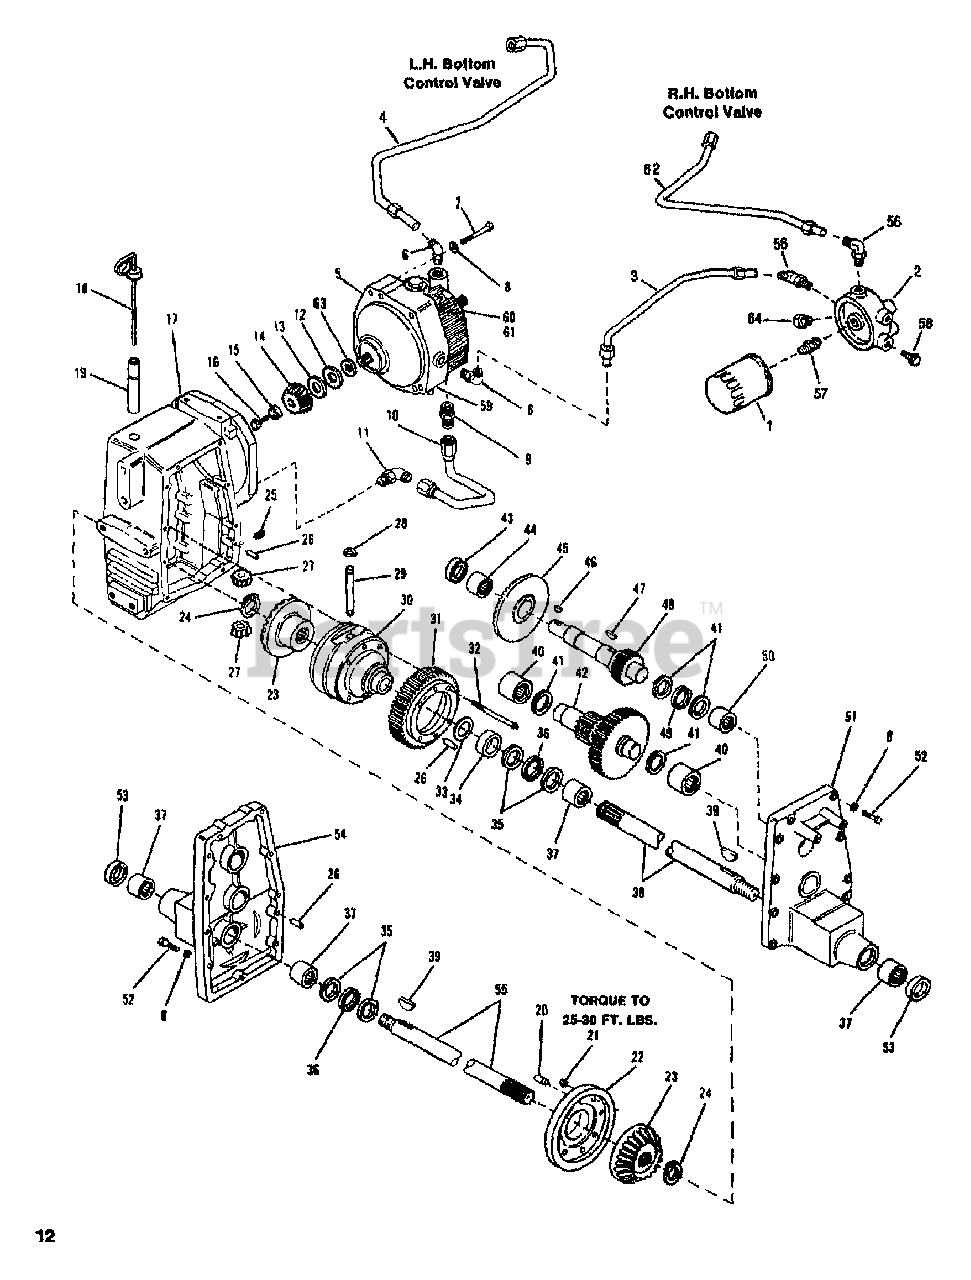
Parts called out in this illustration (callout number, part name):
1	FILTER-OIL
3	ASSM-RETURN TUBE
4	ASSM-TUBE
5	TRANSMISSION-HYDRO
6	ELBOW
7	SCR-HH 3/8-16X2.75 G5 ZP
8	WASHER-LK .375 @ DEPL
9	CONNECTOR
11	ELBOW
12	WASHER-SHIM
13	WASHER-SHIM
14	PINION-BEVEL
15	SPACER-1.0X.25X.25
16	SCR-HH 1/4-20X.625 G5 ZP
17	HOUSING-TRANSAXLE
18	DIPSTICK
20	PIN-.312X.75
21	NUT-HEX/LK 5/16-18 G5ZP
22	COVER-DIFFERENTIAL
23	GEAR-23T
24	RING-HEAVY EXT HD 1.0 ID
25	PLUG-PIPE
26	PIN-DOWEL .375X1.00 ZP
27	PINION-10T
28	RING-RETAIN .625 ID
29	KIT-PINION SHAFT
30	CARRIER-DIFFERENTIAL
31	GEAR-AXLE 47T
32	SCR-HFLK 5/16-18X4.00 ZP
33	SHIM-1.875X1.013X.015
34	SPACER-1.5X1.01X.45
35	RACE-THRUST
36	BEARING-THRUST
37	BEARING-NEEDLE
38	AXLE-RH
39	KEY-WOODRUFF .312X1.12
40	BEARING-NEEDLE
41	RACE-THRUST
42	ASSM-GEAR CLUSTER
43	SEAL-OIL
44	BEARING-NEEDLE
46	KEY-WOODRUFF .25X.75
47	KEY-WOODRUFF .25X1
48	ASSM-PINION SHAFT
49	BEARING-THRUST
50	BEARING-NEEDLE
51	COVER-TRANSAXLE RH
52	SCR-HH 3/8-16X1.5 G5 ZP
53	SEAL-OIL
54	COVER-TRANSAXLE LH
55	AXLE-LH
56	ELBOW
57	COUPLING
59	SEAL-CONTROL SHAFT
60	SEAL-OIL
61	SHIELD-GRASS
62	ASSM-TUBE
63	WASHER-1.0X.64X.029
64	PLUG-PIPE
